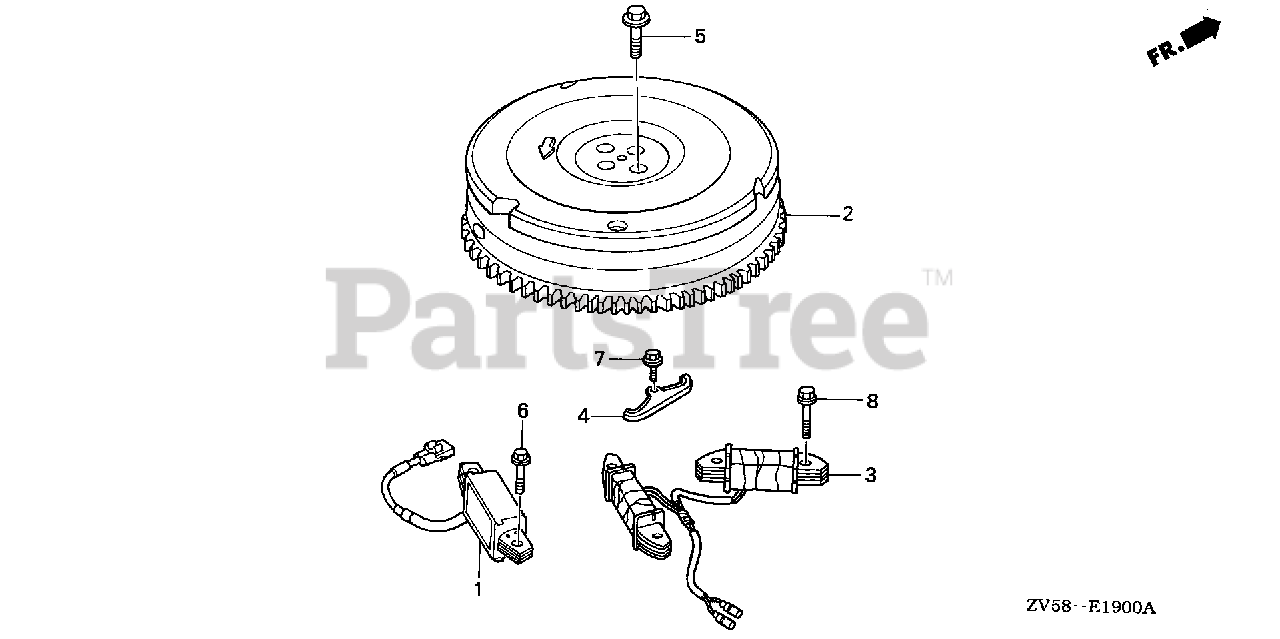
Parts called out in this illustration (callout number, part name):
1	COIL ASSY., EXCITER
2	FLYWHEEL *TBLACK* (BLACK)
3	COIL ASSY., CHARGE (12V/10A)
4	HOLDER, WIRE (B)
5	BOLT, FLANGE (10X25)
6	BOLT, FLANGE (6X25)
7	BOLT, FLANGE (6X12)
8	BOLT, FLANGE (6X32)
